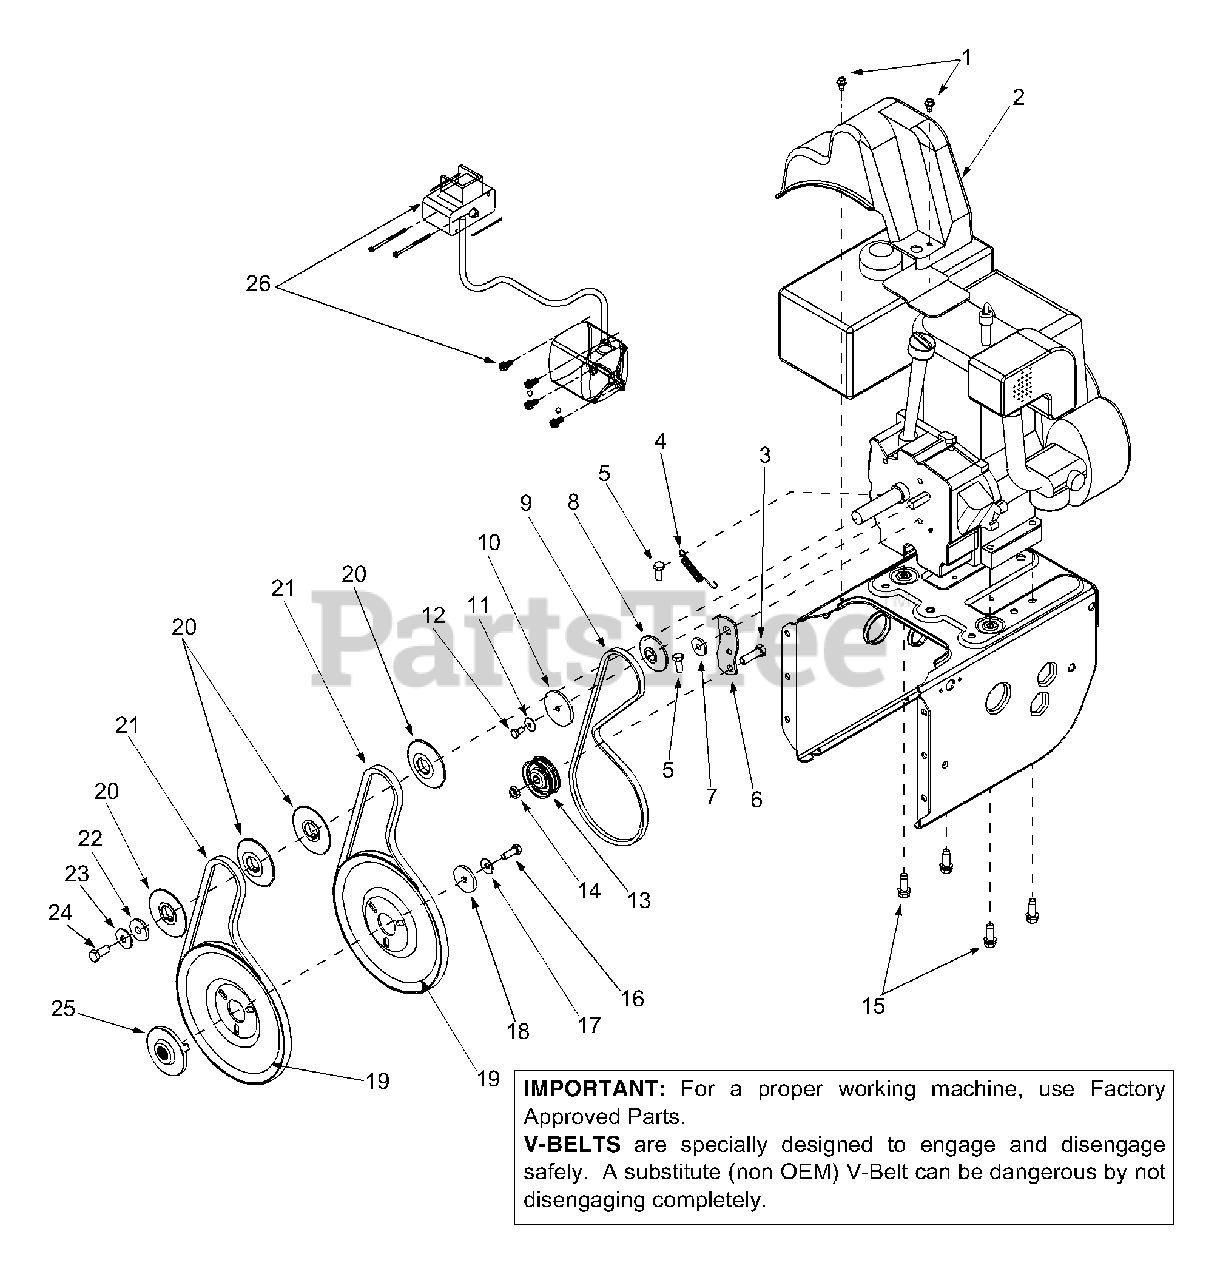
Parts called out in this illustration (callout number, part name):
1	Hex Washer Screw 1/4-20 x .50
2	Belt Cover
3	Hex Cap Screw 3/8-16 x 1.25
4	Spring Extension
5	Hex Screw 5/16-24 x .75
8	Pulley Half
9	Belt
10	Pulley Half
11	Bell Washer
12	Hex Cap Screw
13	Flat Idler
14	Lock Jam Nut 3/8-16
15	Hex Washer Screw 3/8-16 x 1.0
16	Hex Lock Screw 5/16-24 x .875
17	Bell Washer .340 ID x .872 OD
18	Flat Washer .341 ID x .50 OD
19	Pulley Auger
20	Pulley Half
21	V-Belt
22	Flat Washer
23	Bell Washer .39 ID x 1.13 OD
24	Hex Cap Screw 3/8-24 x .875
25	Pulley Adapter
26	Electric Start
